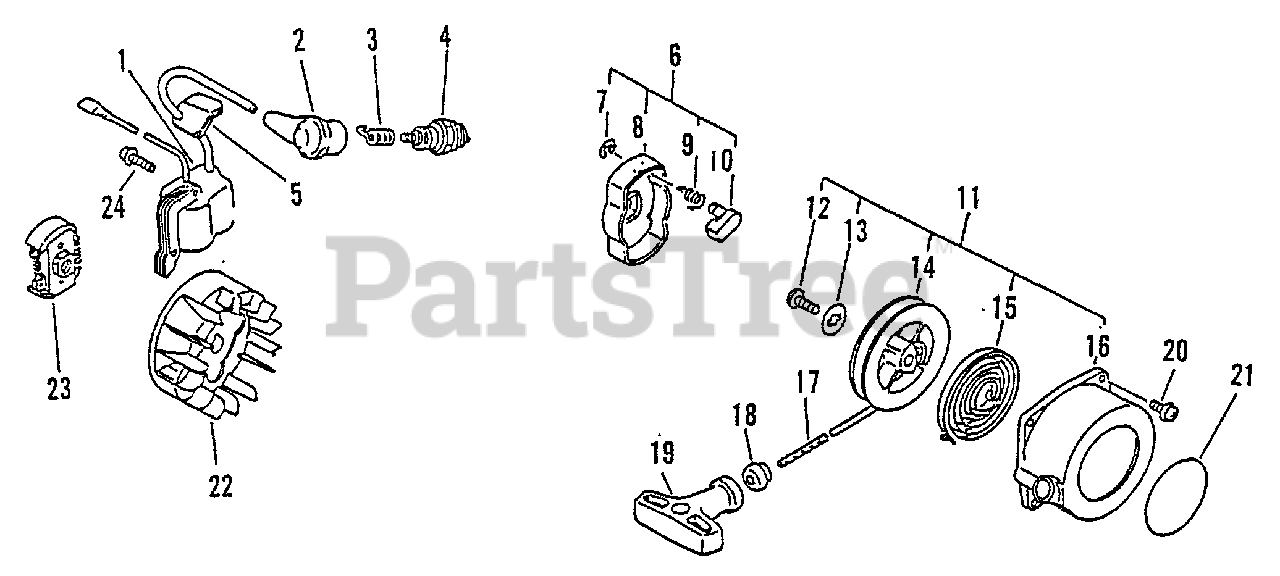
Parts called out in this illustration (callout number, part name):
1	COIL, IGNITION
2	CAP, SPARK PLUG
3	TERMINAL, SPARK PLUG CAP
4	SPARK PLUG -- BPM-7A
5	GROMMET
6	STARTER PAWL ASSY
7	RING, RETAINING - 4
8	CATCHER, PAWL
9	SPRING, RETURN
10	PAWL, STARTER
11	STARTER ASSY
13	WASHER
14	REEL, ROPE
15	SPRING, REWIND
16	CASE, STARTER
17	ROPE, STARTER - 3X890
18	GUIDE, ROPE
19	GRIP, STARTER
20	SCREW - 4X16
21	LABEL - ECHO
22	FLYWHEEL
23	CLUTCH ASSY
24	SCREW - 4X22
